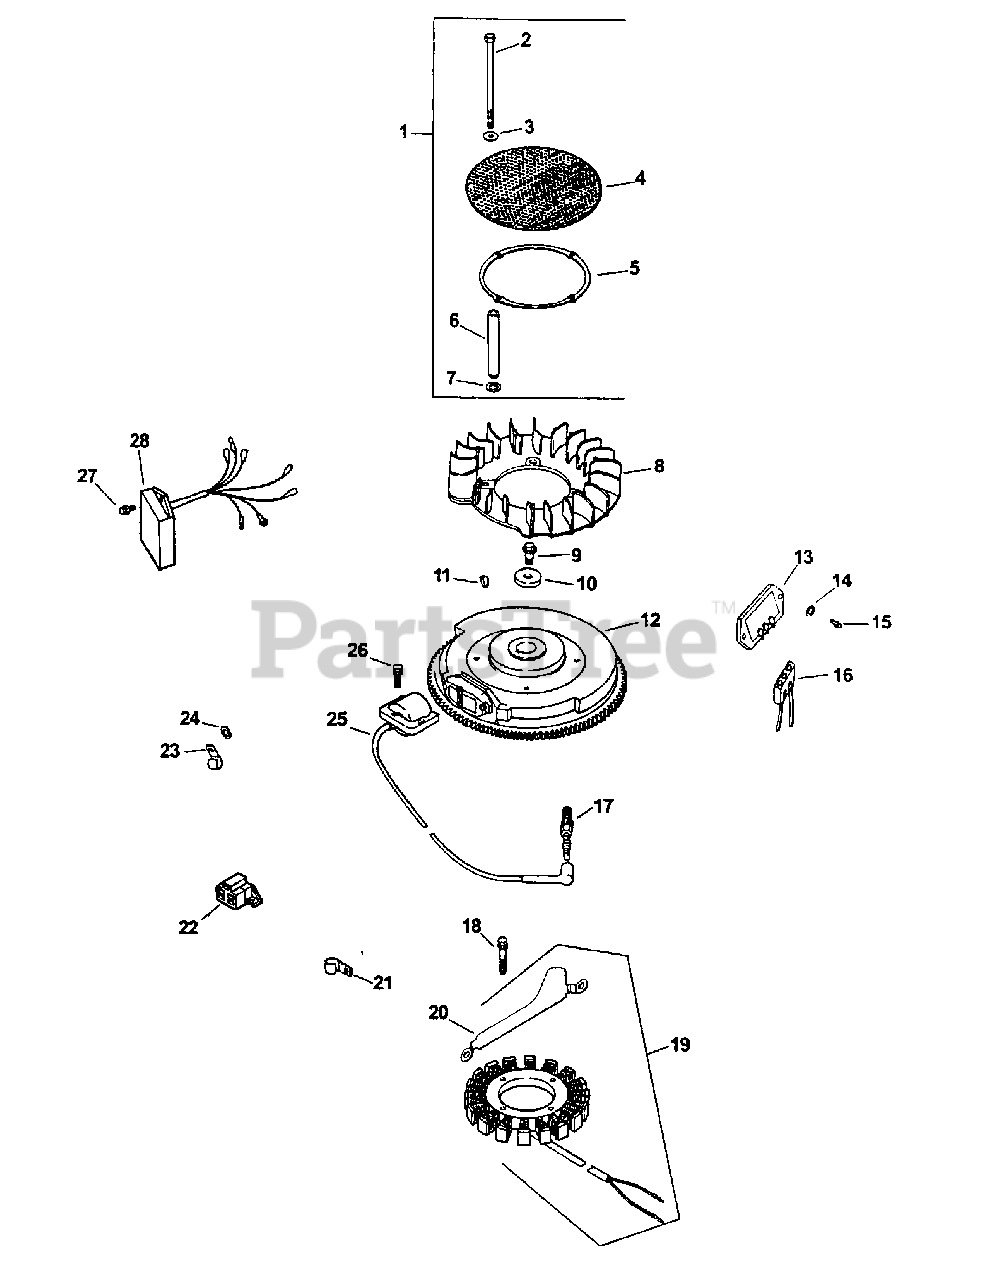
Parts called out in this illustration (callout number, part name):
1	Kit, Chopper Screen
2	Screw, Hex Cap
3	Washer, Plain 1/4"
4	Screen, Grass
5	Ring, Support
6	Spacer, Grass Screen
7	Washer, Spring 10mm
8	Fan
9	Screw, Hex Flange
10	Washer, Plain 3/8"
13	Rectifer - Regulator
14	Washer, Plain 3/16"
15	Screw, Phillips Head 11-16 x 7/8"
16	Connector (3 Contact)
17	Spark Plug
18	Screw, Hex Cap
19	Kit, 15 Amp Stator
20	Bracket, Stator Wire
21	Clip, Cable
22	Connector (5 Contact)
23	Clip, Cable
24	Washer, Plain 1/4"
25	Module Ignition
26	Screw, Thread Forming
